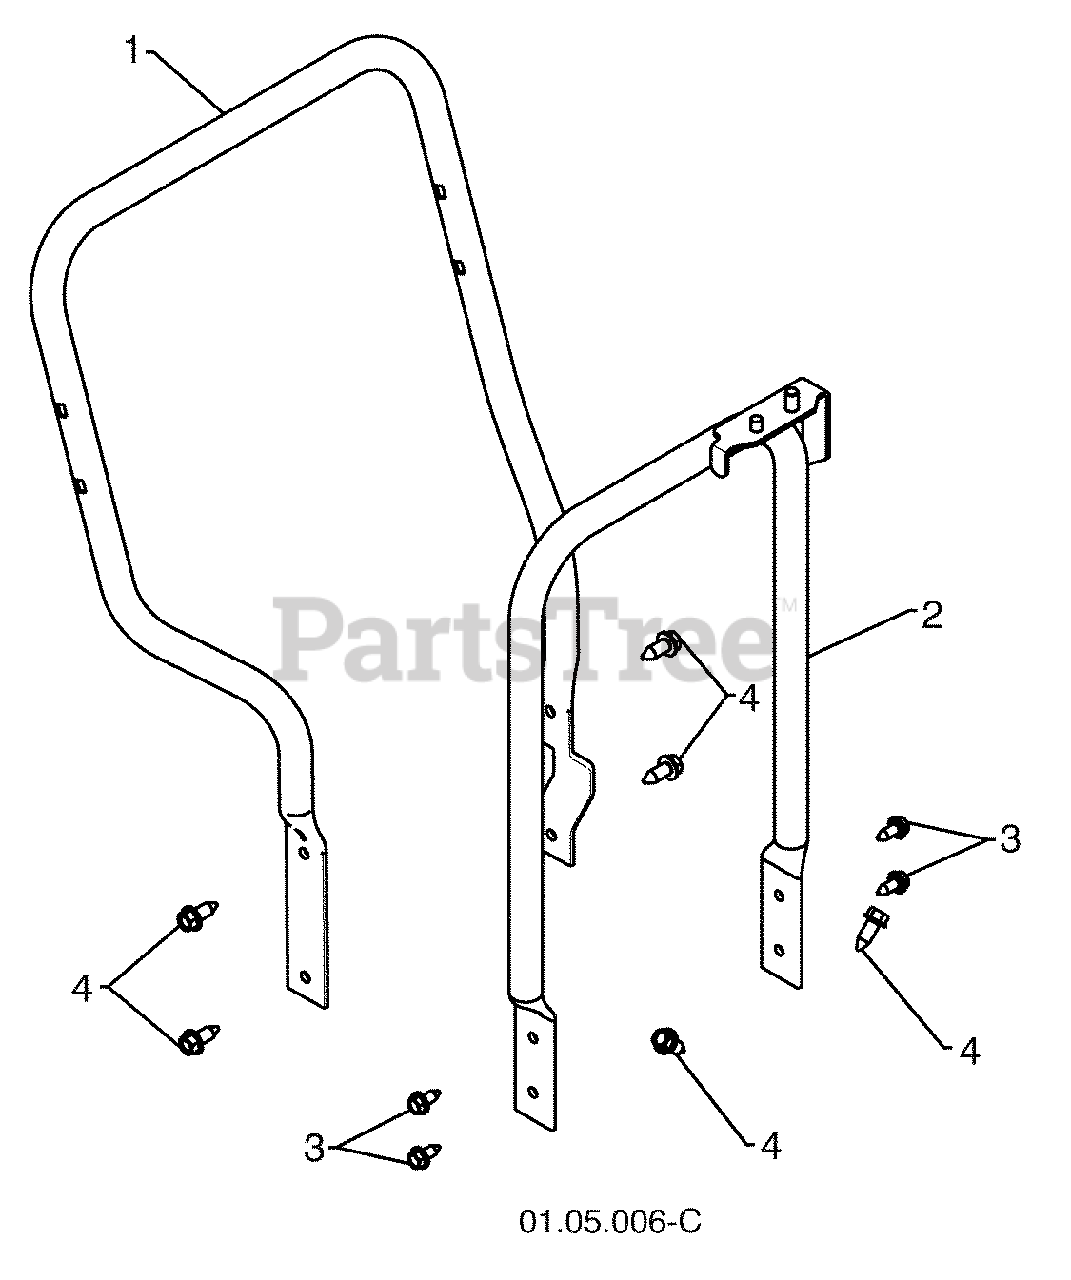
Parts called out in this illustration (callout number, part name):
1	LOWER TUBE GRAY
2	PIVOT SUPPORT
3	BOLT 5/16-18 X .750
4	SCREW 3/8-16 X 1.00
